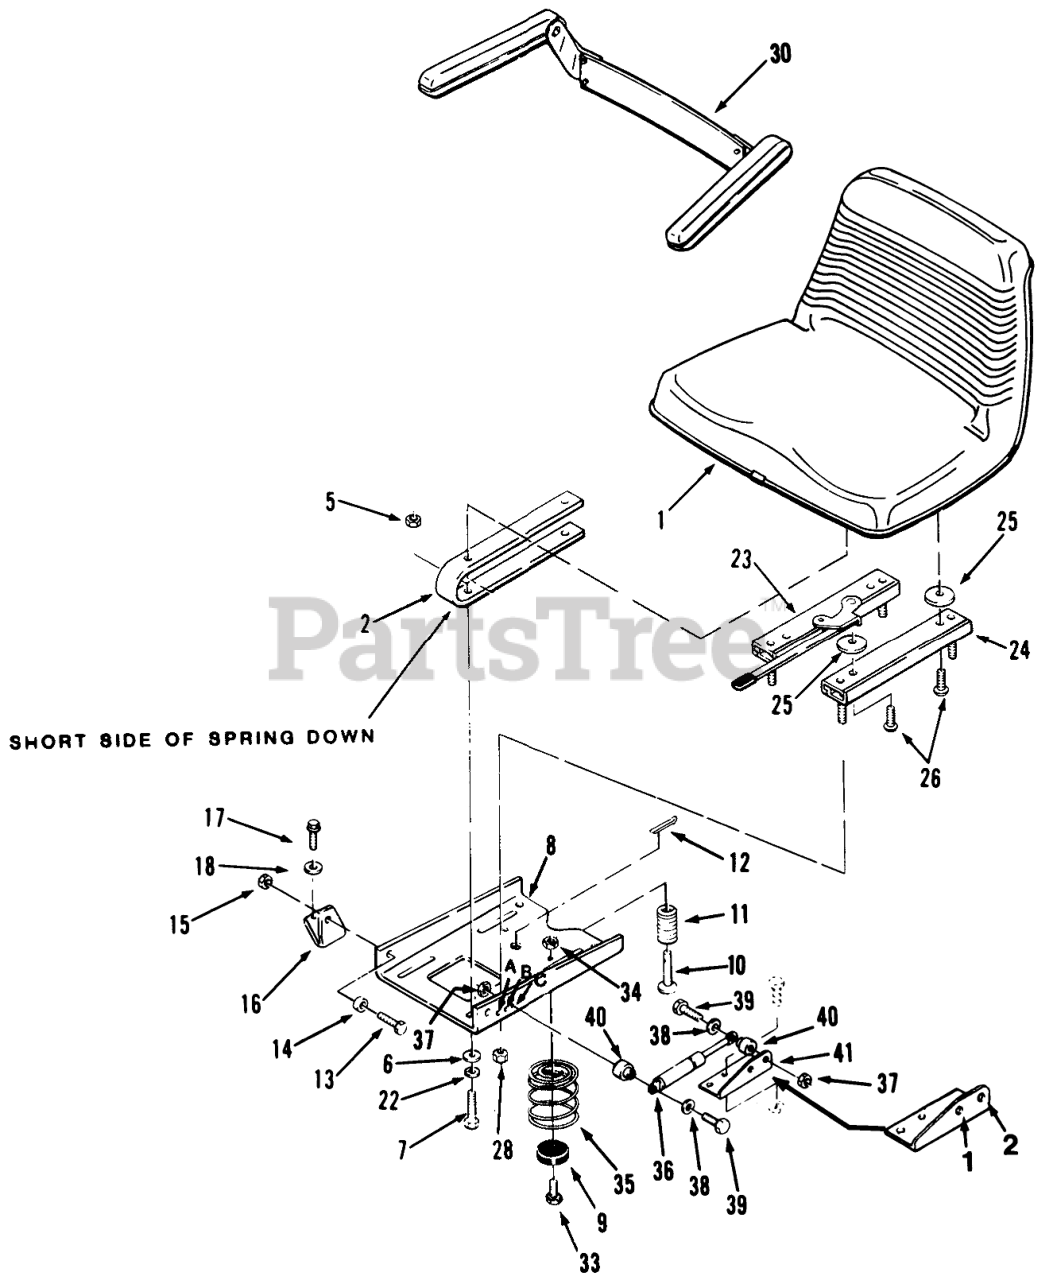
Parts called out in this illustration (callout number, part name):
1	Seat
2	Seat Spring
5	Nut
6	WASHER-PLAIN
7	HHCS
8	PLATE-SEAT PIVOT B
9	BUMPER
11	SPRING-SEAT SWITCH
12	PIN-COTTER
13	HHCS
14	BUSHING
15	E.S. Nut 5/16-18
16	Bracket-Pivot RH
17	Bolt
18	WASHER 5/16 SAE
22	WASHER-LOCK
23	Adjuster-Seat
24	ADJUSTER-R.H. SEAT
25	SPACER-NYLON
26	Screw
28	Nut
30	KIT-ARMREST
33	Bolt
34	NUT-LOCK, NI
35	SPRING
36	GAS SPRING
37	NUT-LOCK, NI
38	WASHER-FLAT
39	SCREW-HH
40	SPACER
41	BRACKET-CYLINDER R
